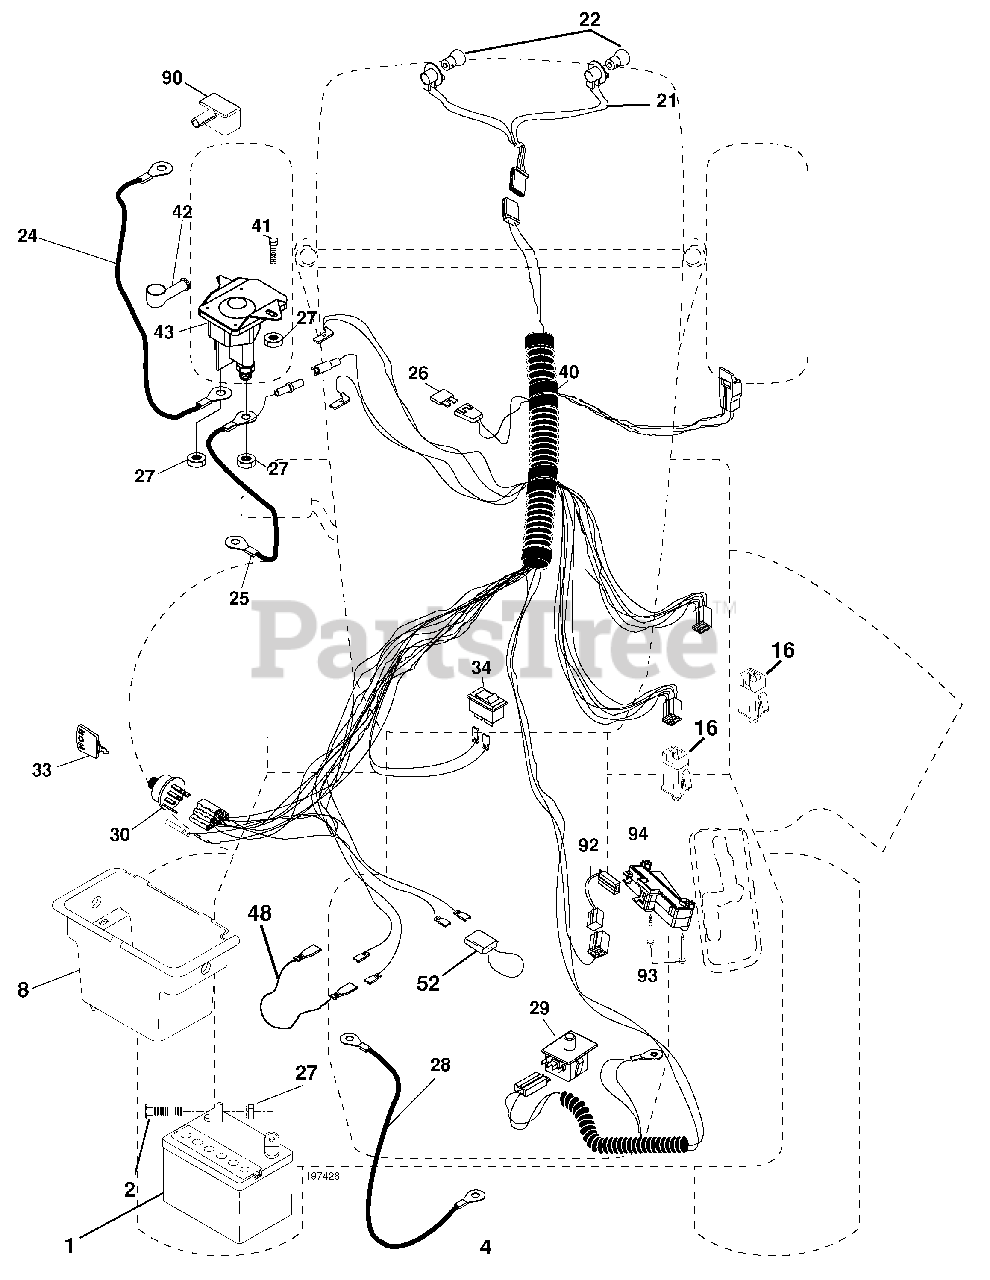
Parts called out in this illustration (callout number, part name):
1	Battery
2	Bolt Hex Hd 1/4-20 unc x 3/4
8	Box Battery
16	Switch Interlock
21	Harness Asm Light W/4152j
22	Bulb Light #1156
24	Cable Battery 6 Ga. 11"red
25	Cable Battery
26	Fuse 20 AMP
27	Nut Keps Hex 1/4-20 unc
28	Cable Ground 6 Ga. 12" Black
29	Switch Seat
30	Switch Ign
33	Key Ign
34	Switch Light/Reset
40	Harness Ign
41	Bolt Blk Fin Hex 1/4-20
42	Cover Terminal Red
43	Solenoid
48	Adapter Ammeter
52	Protection Wire Loop
90	Cover Terminal Battery
92	Harness Pigtail
93	Screw Plastite 10-14 x 2.0
94	Module Reverse ROS
